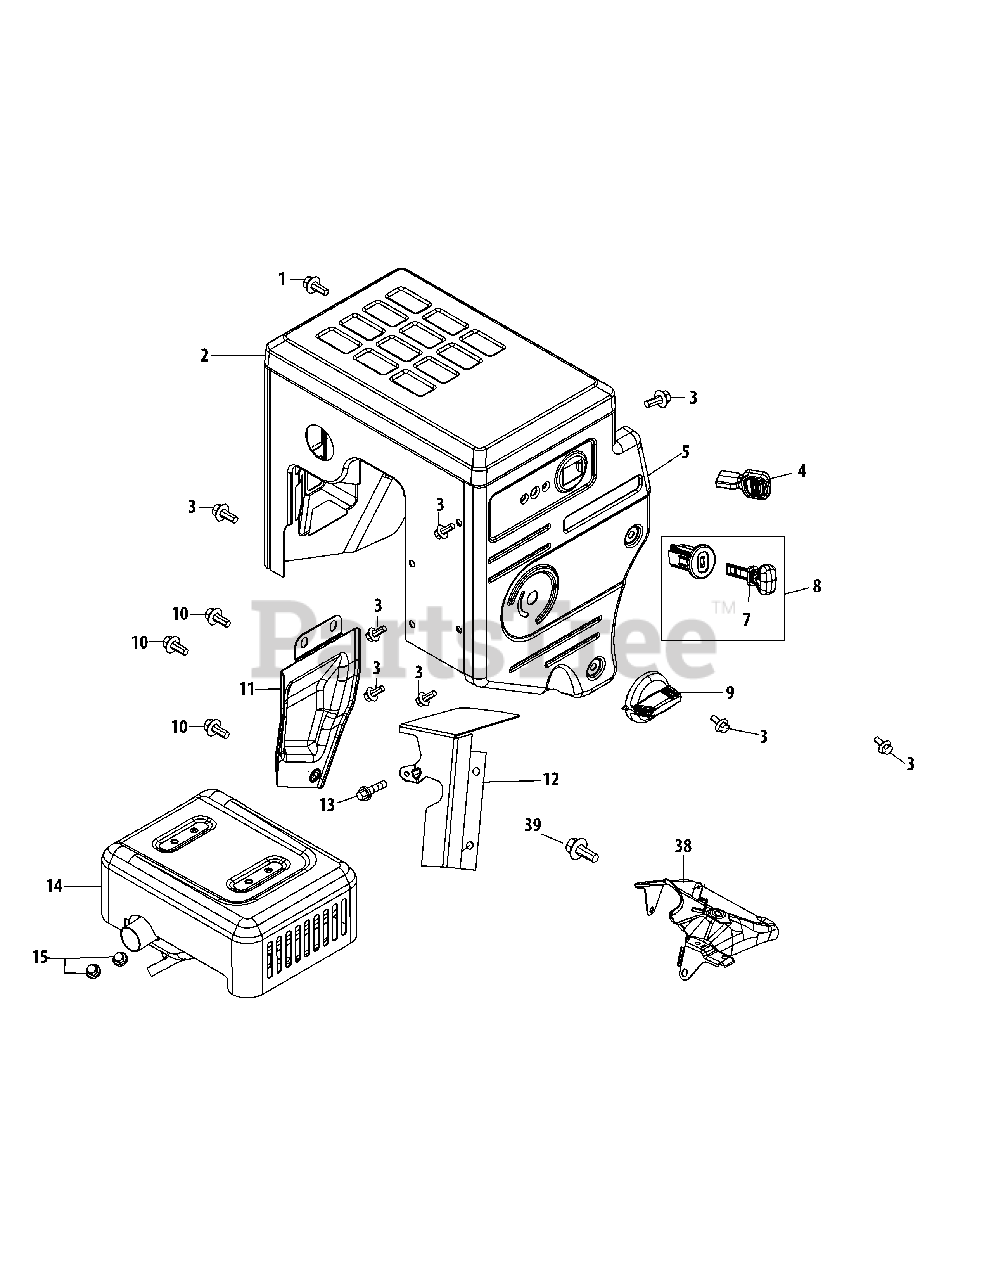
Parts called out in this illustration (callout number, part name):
1	Bolt M6×12
2	Muffler Shield
3	Bolt M6×12
4	Throttle Control Knob
5	Control Panel
7	Key
8	Key Switch Assembly
9	Choke Knob
10	Bolt M6×10
11	Exhaust Pipe Shield
12	Carburetor Heat Shield
13	Bolt M6×16
14	Muffler Assembly
38	Throttle Control Assembly
39	Bolt M6×12
